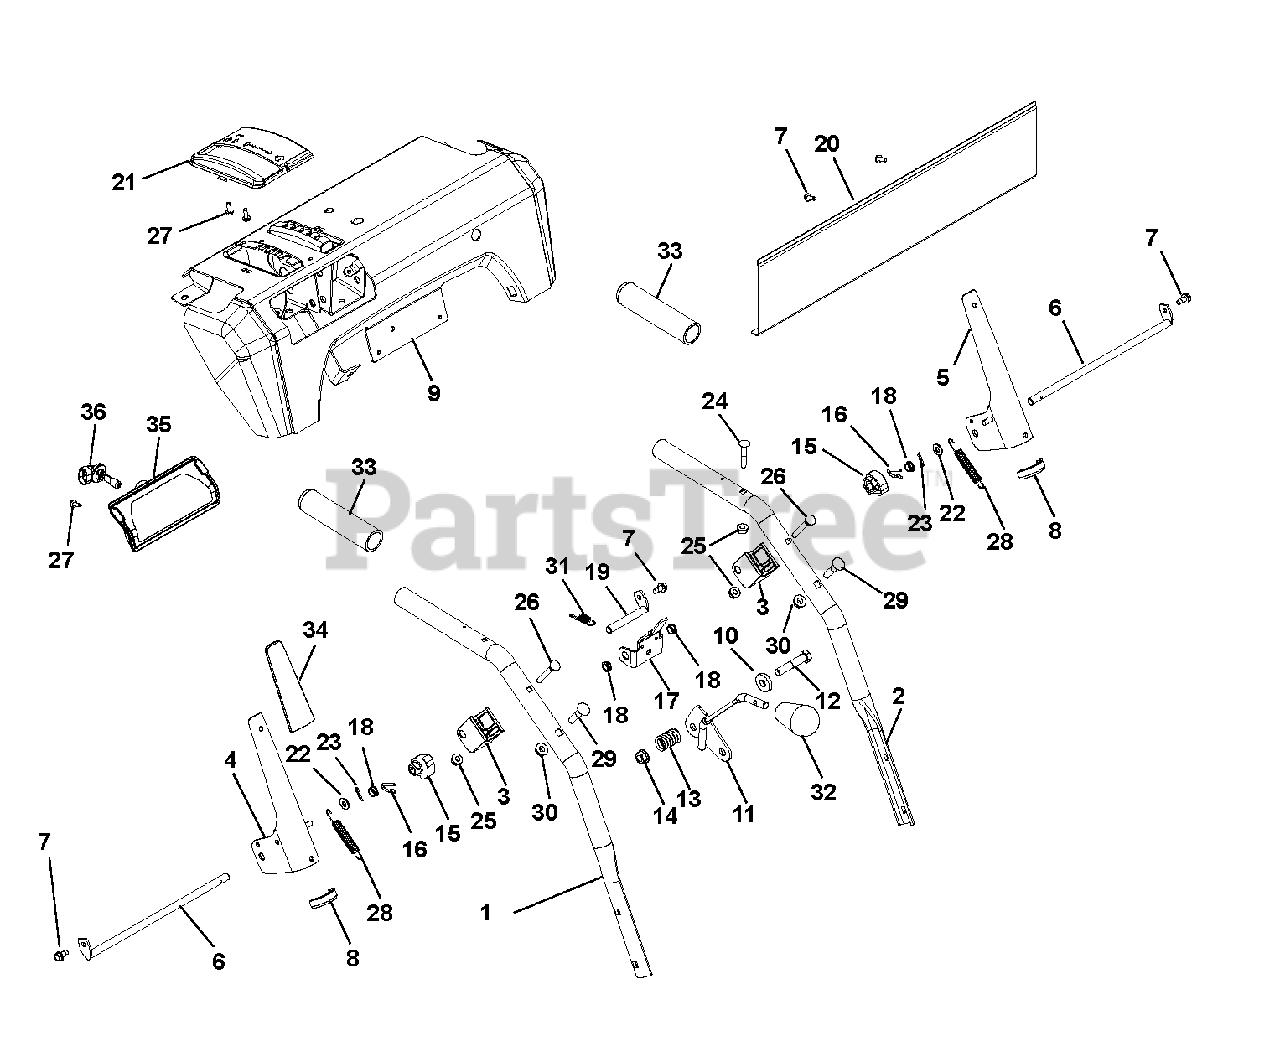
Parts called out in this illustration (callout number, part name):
1	Handlebar, Upper, Right Hand
2	Handlebar, Upper, Left Hand
3	Clutch Paddle Block
4	Clutch Handle, Right Hand
5	Clutch Handle, Left Hand
6	Rod, Paddle Mount
7	Screw, Tapping Hex Washer Head Thread Rolling .25-20 x .50
8	Edging, Clutch Handle
9	Control Panel with Decal
10	Washer, Flat Steel .406 x 1.00 x .188
11	Lever, Shift
12	Bolt, Hex .38-16 x 2.00
14	Nut, Locking Top Flange .38-16
15	Cam, Interlock
16	Pin, Spring Clip
17	Interlock Arm
18	Bushing, Polyliner
19	Rod, Pivot
20	Brand Plate
21	Shift Bezel
22	Washer, Flat Steel .281 x .62 x .065
23	Pin, Hair, Internal .06 x .18 x .77
24	Bolt, Round Head Extra Long Square Neck .25-20 x 1.25
25	Nut, Locking Top Flange .25-20
26	Bolt, Round Head Extra Long Square Neck .25-20 x 2.00
27	Screw, Tapping Hex Head Boss #10 x .50
29	Bolt, Round Head Square Neck .31-18 x 1.50
30	Nut, Locking Top Flange .31-18
33	Handle Grip
34	Sleeve, Clutch Handle
35	Headlight Assembly (Includes Item 36)
36	Bulb, Light (Included in Item 35)
